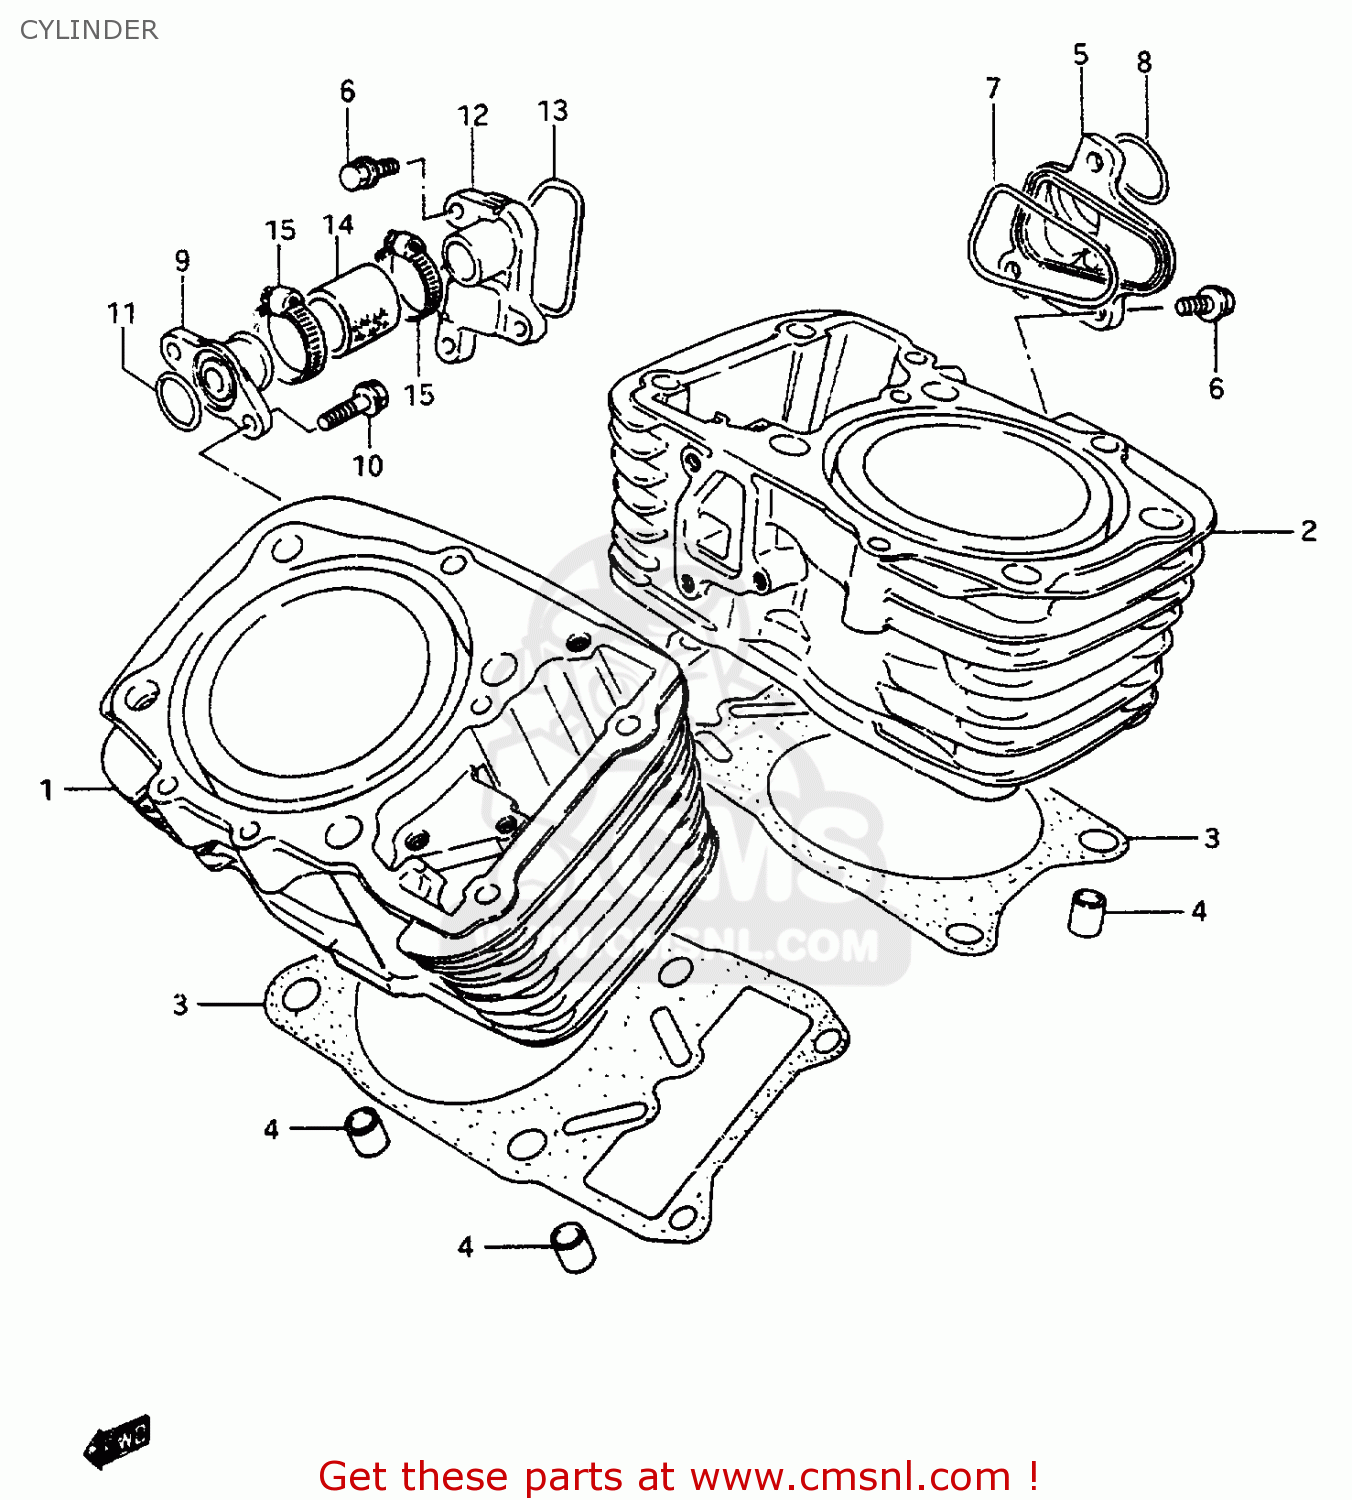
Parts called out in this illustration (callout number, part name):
1	CYLINDER,FR
2	CYLINDER
3	GASKET,CYLINDER
4	PIN
5	CHAMBER,WATER,INLET
6	BOLT
7	O RING,INLET WATER CHAMBER
8	O RING(D:2.3,ID:24.4)
9	UNION,WATER INLET
10	BOLT
11	O RING(D:2.4,ID:15.8)
12	CHAMBER,WATER OUTLET
13	O RING,OUTLET WATER CHAMBER
14	HOSE,RADIATOR JOINT NO.1
15	CLAMP
